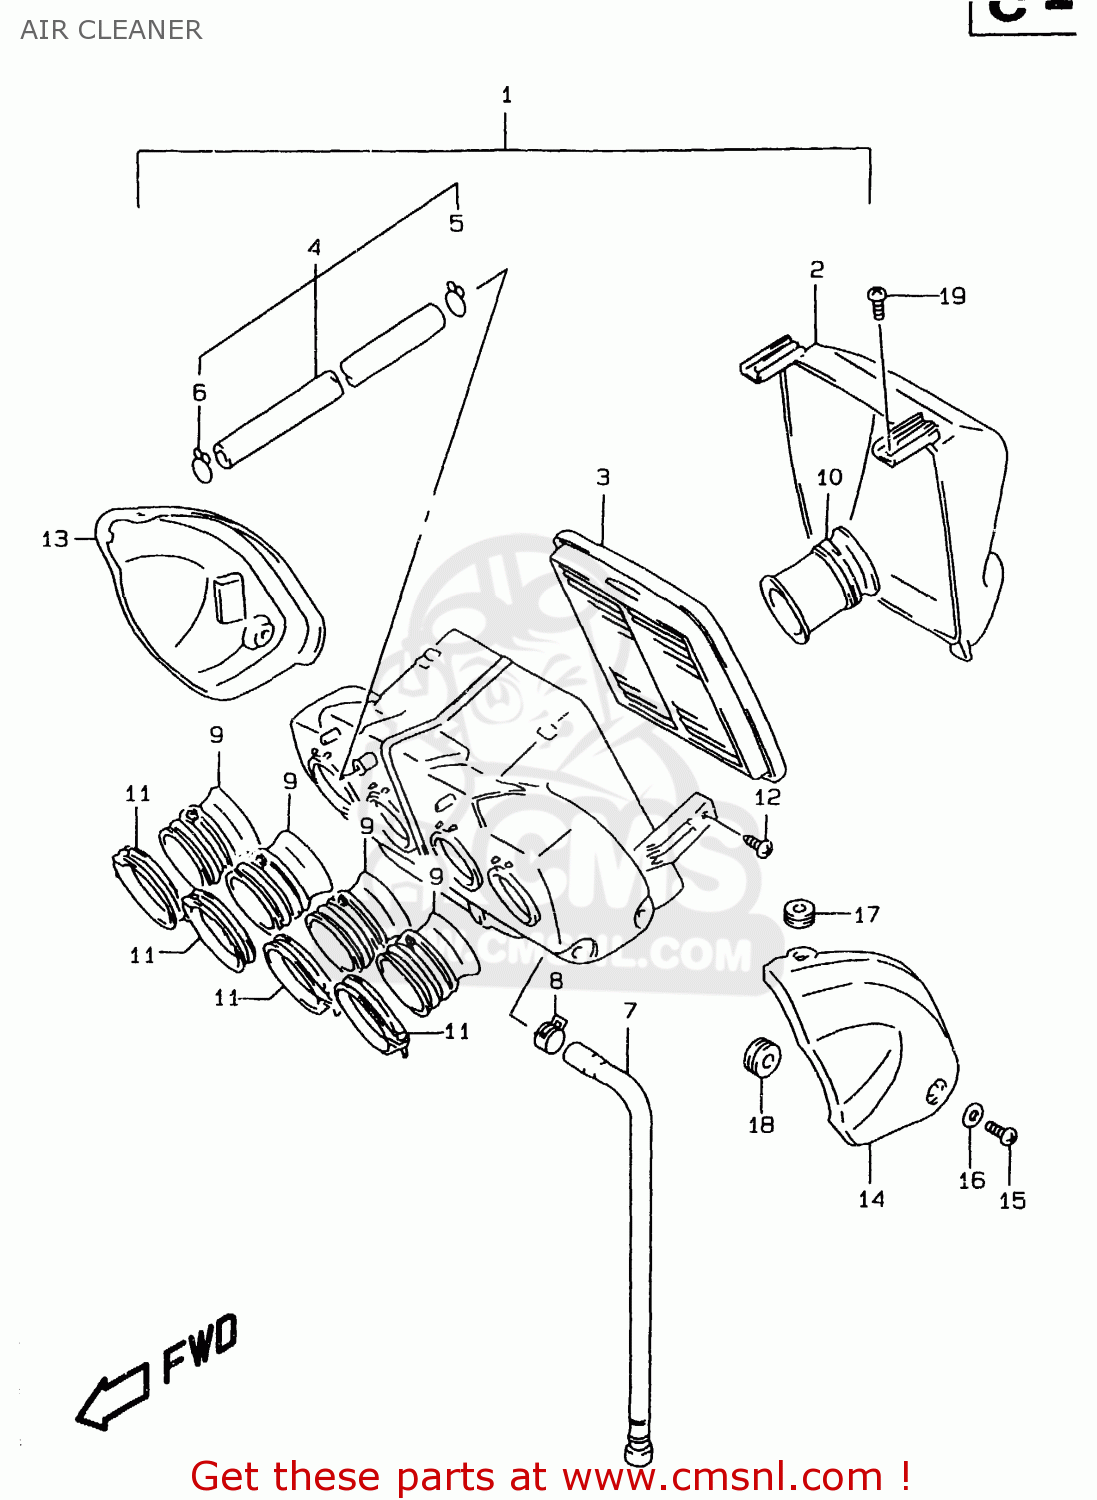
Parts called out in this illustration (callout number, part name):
1	CLEANER ASSY,AIR
2	CAP,AIR CLEANER
3	FILTER,AIR
4	TUBE,BREATHER
5	CLIP
6	CLIP
7	TUBE,DRAIN
8	CLIP
9	TUBE,OUTLET
10	TUBE,INLET
11	CLAMP
12	SCREW
13	COVER COMP,AIR CLEANER,RIGHT
14	COVER COMP,AIR CLEANER,LEFT
15	SCREW(5X14)
16	WASHER
17	CUSHION
18	CUSHION
19	SCREW 6X12
